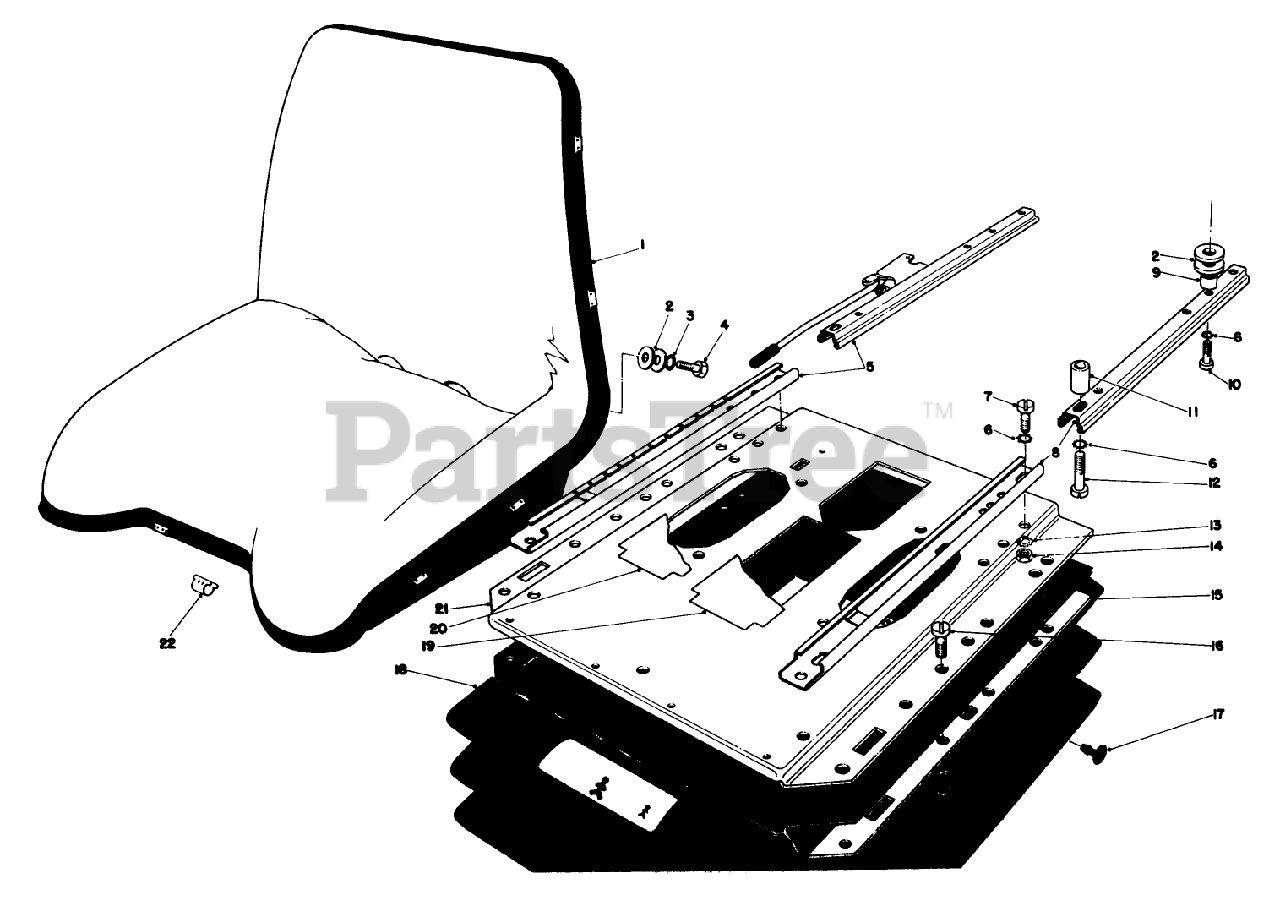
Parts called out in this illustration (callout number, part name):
1	Seat Bucket Complete
2	Washer 13 MM
3	Serrated Washer
4	Capscrew 7/16-20 U.N.F.
5	Fender
6	Serrated Washer
7	KNOB-THROTTLE
8	Adjustment Track
9	Sleeve
10	PLATE-FRONT AXLE R
11	TORQUE STRAP RH R
12	Cylinder Bolt
13	Spring Washer
14	Nut M8
16	Capscrew
17	PULLEY-PTO TRANSM R
18	Rubber Bellows
19	Cover
20	TORQUE STRAP LH R
21	Upper Suspension Plate Complete
22	Clamps Outside
38	Sleeve 14x1x19MM
